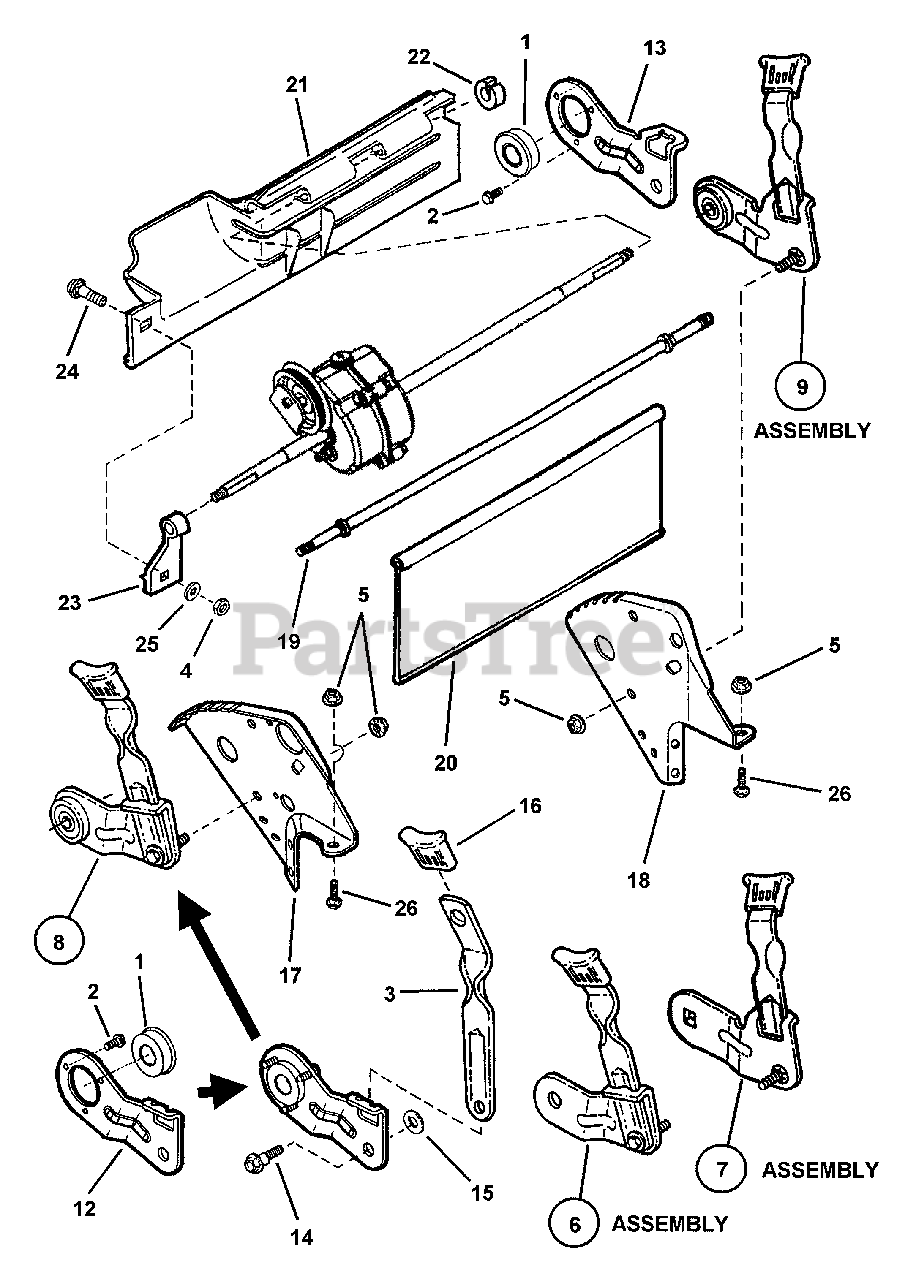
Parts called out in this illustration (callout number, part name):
1	BEARING, 9/16 (Commercial)
2	SCREW, #10-32 x 3/8" Self-Tapping (Torx)
3	LATCH, Height Adjusting (Long)
4	NUT, 1/4-20 Hex, Grade 5
5	NUT, 5/16-18 Hex Flange Lock, Grade 5
6	ASSEMBLY, Wheel Arm (Right Rear) (Round Opening)
7	ASSEMBLY, Wheel Arm (Left Rear) (Square Opening)
8	ASSEMBLY, Wheel Arm (Right Rear)
9	ASSEMBLY, Wheel Arm (Left Rear)
10	ARM, Round Axle End (Round Opening)(Right Rear)(Part of #6)
11	ARM, Square Axle End (Square Opening)(Left Rear)(Part of #7)
12	ARM, Wheel Right Rear
13	ARM, Wheel Left Rear
14	BOLT, 5/16-18 x 1" Shoulder
15	RETAINER, 5/16 Bolt
16	GRIP, Latch
17	BRACKET, Right Rear Wheel
18	BRACKET, Left Rear Wheel
19	AXLE
20	GUARD, Rear Foot
21	GUARD, Rear Foot
22	RING
23	SUPPORT, Foot Guard
24	BOLT, 1/4-20 x 1/2" Short Neck Carriage, Grade 5
25	WASHER, 1/4 Internal Tooth Lock
26	BOLT, 5/16-18 x 1/2" Short Neck Carriage, Grade 5
